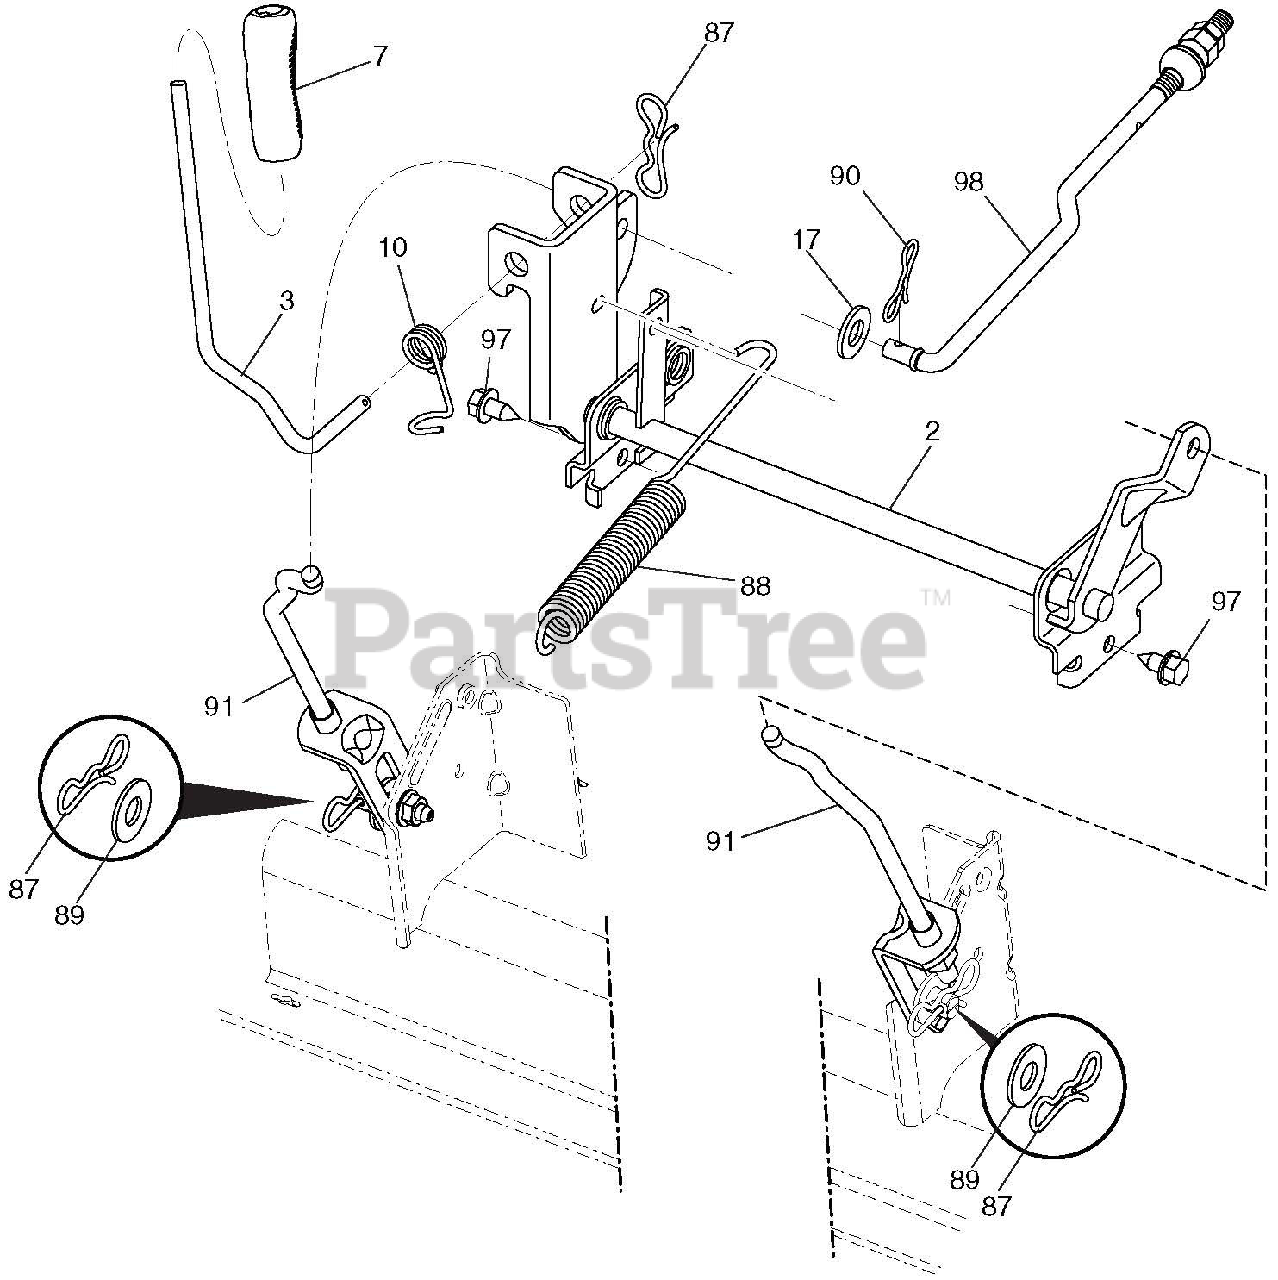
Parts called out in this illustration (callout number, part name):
2	SHAFT ASM., LIFT
3	LEVER.LIFT.HANDLE.LT
7	GRIP LEVER 5625 LD BLACK 428
10	SPRING.TORSION.HANDLE.LIFT
17	Washer 13/32 x 13/16 x 12 Ga.
87	PIN.COTTER.7/16.BOW TIE LOCK
88	SPRING.LIFT ASSIST
89	WASHER.CLEAR ZINC
90	PIN.COTTER.5/16.BOW TIE LOCK
91	LINK.LIFT.SUSP.MOWER.REAR
97	SCREW.HEXWSH THDR3/8-16X3/4.BL
98	LINK.LIFT.SUSP.MOWER.FRONT
